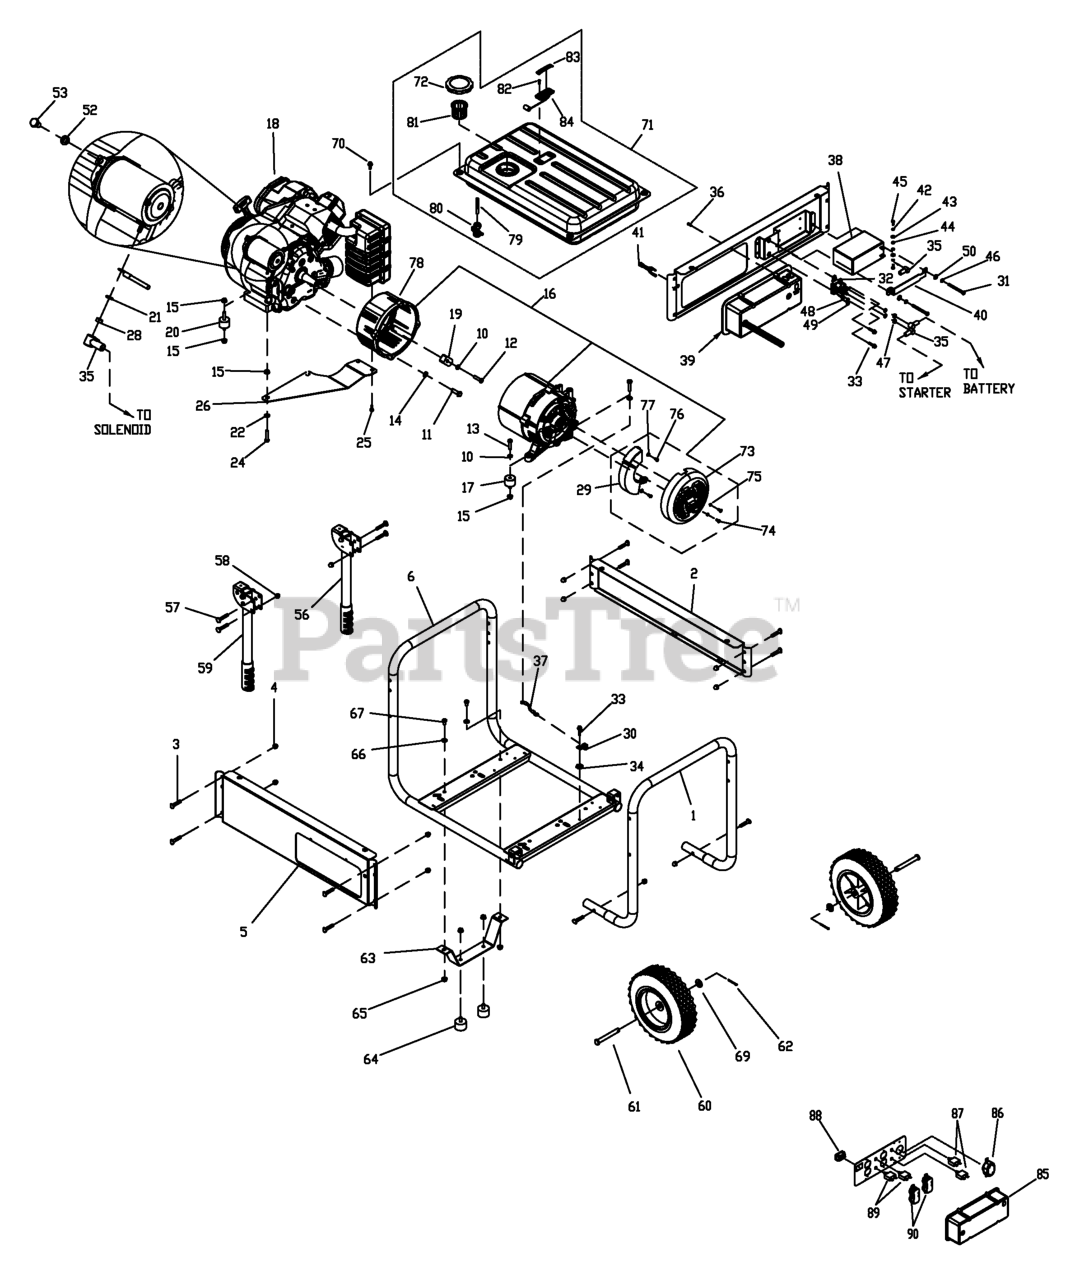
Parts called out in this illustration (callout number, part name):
1	CRADLE END
2	BACK RAIL
3	CURVED HEAD BOLT 5/16-18 X 1.625" LONG
4	CAP NUT LOCKING 5/16 -18 THREAD
5	PANEL RAIL, ELECTRIC START
6	ASSY, CRADLE BASE
10	WASHER, LOCK M8-5/16
11	SCREW, HHC 3/8-16 X 1-1/4 G5
12	SCREW, HHC 5/16-24 X 1-1/4 G5
13	SCREW, HHC 5/16-18 X 1-1/4 G5
14	WASHER, LOCK M10
15	NUT LOCK FLG 5/16-18
16	ALTERNATOR, 70 00W, SAE, BRUSHLESS
17	VIB MOUNT 1.38 X 1.0 X 5/16-18 MALE / FEMALE
18	ASSEMBLY, ENGINE GH-410
19	BRACKET, MOUNT 7KW ALTERNATOR
20	VIB MOUNT RUBBER 1.38 X 1.0 X 5/16-18 M/M
22	WASHER, FLAT 5/16-18-M8
24	SCREW, HHC 5/16-18 X 1-1/2
25	HHFCS M6-1.0 X 16
26	BRACKET, MOUNTING, MUFFLER GH410
28	NUT, HEX M6-1.0 G8
29	CAPACITOR, VOLTAGE REGULATOR
30	LUG, SOLDERLESS #2-#8 X 17/64 CU
31	SCREW, HHC M6-1.0 X 70
32	CONTACTOR, STARTER SOLENOID
33	ASSY, GROUND WIRE ALTERNATOR TO BASE
34	WASHER, LOCK SPECIAL 1/4"
35	BOOT, VINYL-STARTER CONTACTOR
36	SCREW, PPPH #8-16 X 1/2" BZC
38	BATTERY, 12V 10Ah
39	RECEPTACLE PANEL 30A RND W/HR MTR
40	BRACKET, BATTERY HOLD DOWN
41	ASSY, DC POWER JACK
42	WASHER, LOCK #10
43	WASHER, FLAT #10 ZINC
44	NUT, HEX M5-0.8 G8 C LEAR ZINC
45	SCREW, HHC M5-0.8 X 12
46	WASHER, LOCK M6-1/4
47	NUT HEX 1/4-20
48	WASHER, LOCK #8-M4
49	NUT HEX #8-32 STEEL
50	WASHER FLAT 1/4-M6
52	WASHER, LOCK M8-5/16
53	SCREW, HHC M8-1.25 X 12
55	ACCESSORY KIT, 14 GRAY ([I/N’s: 56-69]
56	ASSY, HANDLE LH ORANGE
57	CHB CUSTOM 5 /16-18 X 46mm LONG
58	CAP NUT LOCKING 5/16-18
59	ASSY, HANDLE RH
60	TIRE, 9.5" DIA RUN FLAT PLASTIC / RUBBER
61	AXLE PIN, 1/2" x 4"
62	PIN, COTTER
63	FRAME, BENT FOOT
64	RUBBER FOOT
66	WASHER, FLAT 5/16-M8
67	SCREW, HHC 5/16-18 X 1/2"
69	WASHER, FLAT 1/2"
70	SCREW, HHTT M8-1.25 X 20
71	ASSY, FUEL TANK 8.0 GAL
72	FUEL CAP, VENTED
73	COVER, ALTERNATOR INLET
74	SCREW, HHC M5-0.8 x 1 2
75	WASHER, LOCK M5
76	SCREW, HHC M5-0.8 x 1 6
77	WASHER, FLAT M5
78	ENGINE ADAPTOR, 410c c
79	FILTER, FUEL VALVE
80	VALVE, FUEL SHUTOFF
81	FUEL FILTER
82	SCREW, PFHM M5-0.8 x12
83	PLATE, FUEL GAGE
84	FUEL GAGE, 115mm LONG ARM
85	RECEPTACLE PANEL
86	OUTLET, 30A 12 0 / 250V
87	CIRCUIT BREAKER, 30A 120V
88	HOUR METER
89	CIRCUIT BREAKER, 20A 120V
90	OUTLET, 20A 12 0V DUPLEX
